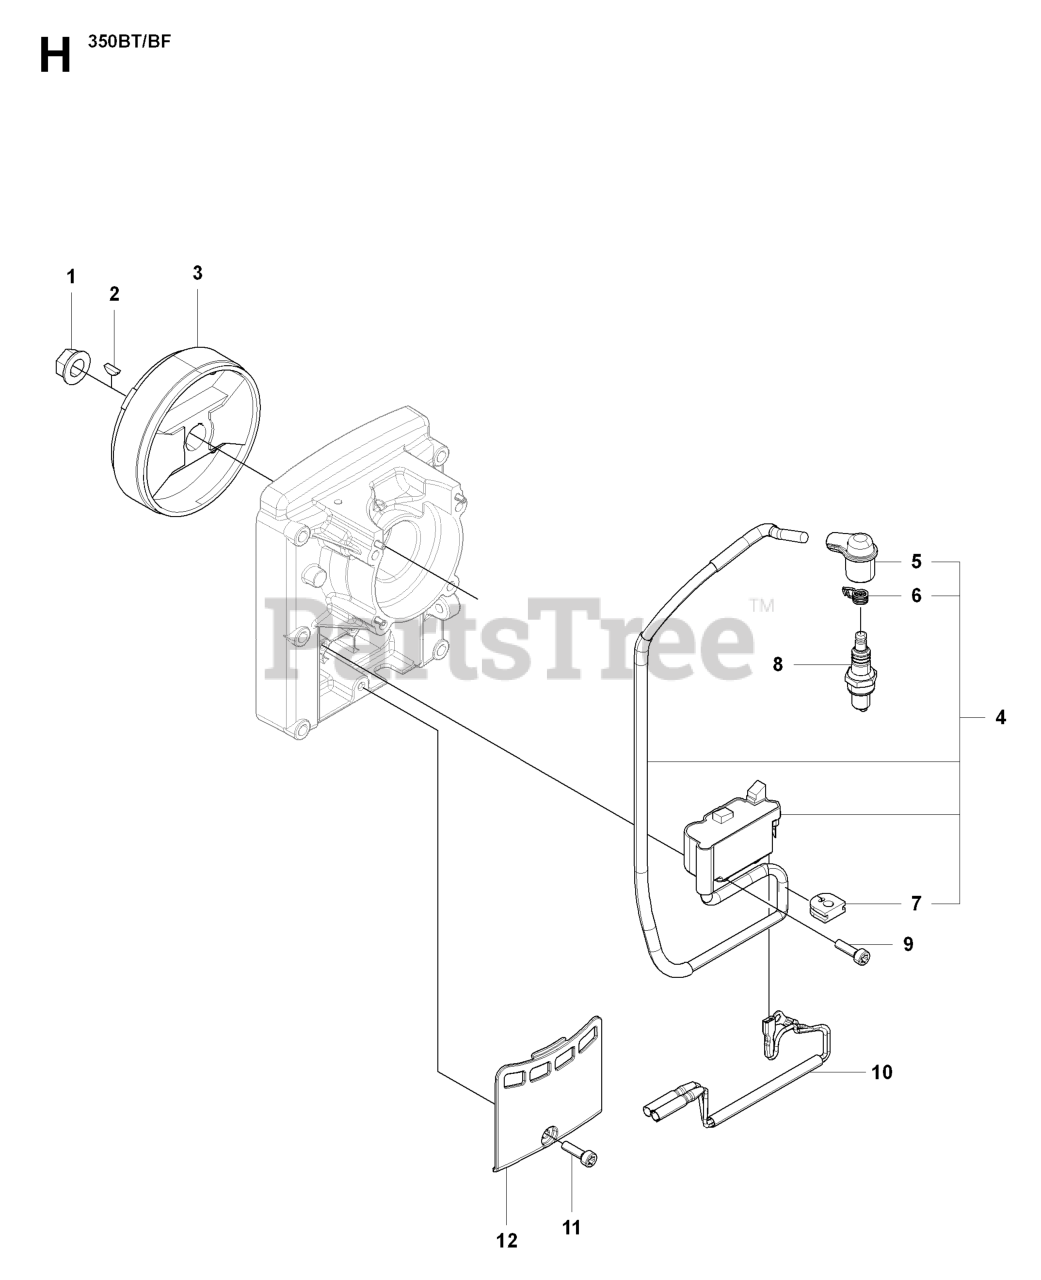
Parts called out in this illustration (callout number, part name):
3	FLYWHEEL
4	IGNITION MODULE ASSY
6	SPRING
7	GROMMET
8	SPARK PLUG TORCH AC7R
